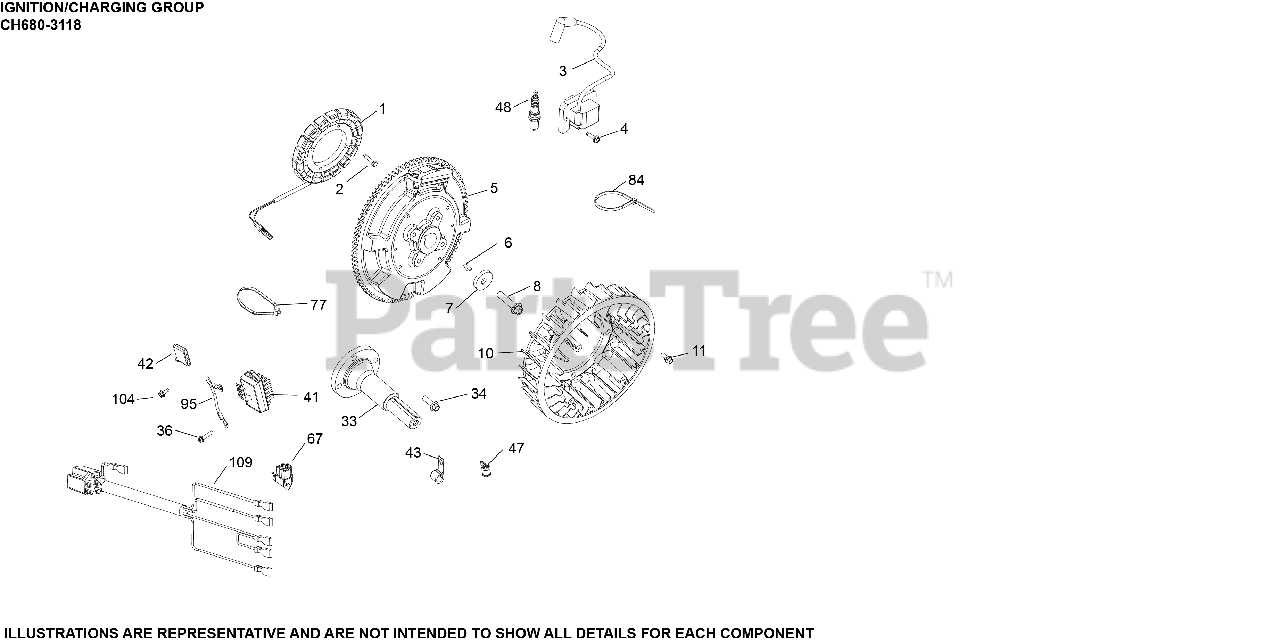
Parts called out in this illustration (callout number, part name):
1	KIT, 25 AMP STATOR ASSY.
1	KIT, 25 AMP CONVERSION
2	SCREW, THREAD FORMING
3	KIT, MODULE IGNTN (CDI FIXED)
4	SCREW, THREAD FORMING
6	KEY, 3/16" X 5/8"
7	WASHER, FLAT 13/32"
8	SCREW, FLG M10X1.5X45 - (#25086361S)
10	FAN USE 24 755 253-S
11	BOLT, SHOULDER
33	SHAFT, FRONT DRIVE
34	SCREW, FLG M8X1.25X25
36	SCREW, HEX FLANGE HI-LO
41	REGULATOR, RECT (20-30AMP, FW W/OVP)
42	CONNECTOR
43	CLIP, CABLE
48	PLUG, SPARK (STD)
67	CONNECTOR
104	SCREW, THREAD FORMING
109	HARNESS, WIRING
